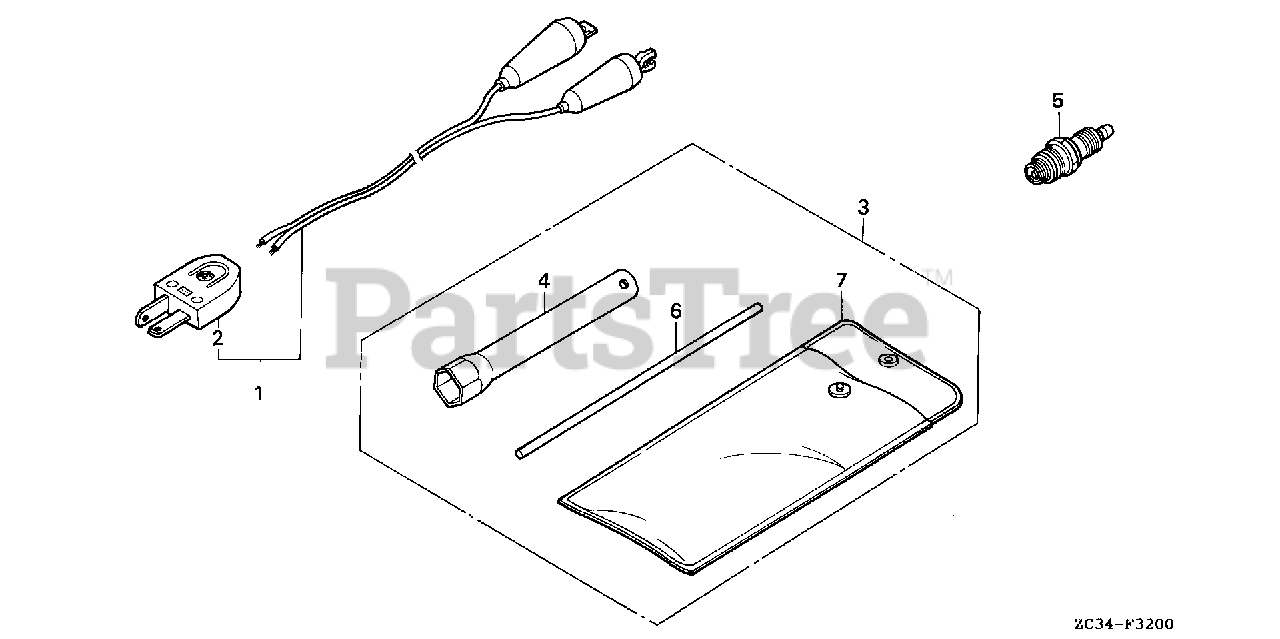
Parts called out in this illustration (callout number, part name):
1	WIRE ASSY., CHARGE (2M)
2	PLUG ASSY., RECEPTACLE
3	TOOL KIT
4	WRENCH, SPARK PLUG (NOT AVAILABLE)
5	SPARK PLUG (BMR6A) (NGK)
6	BAR A, HANDLE
7	BAG, TOOL (160MM)
